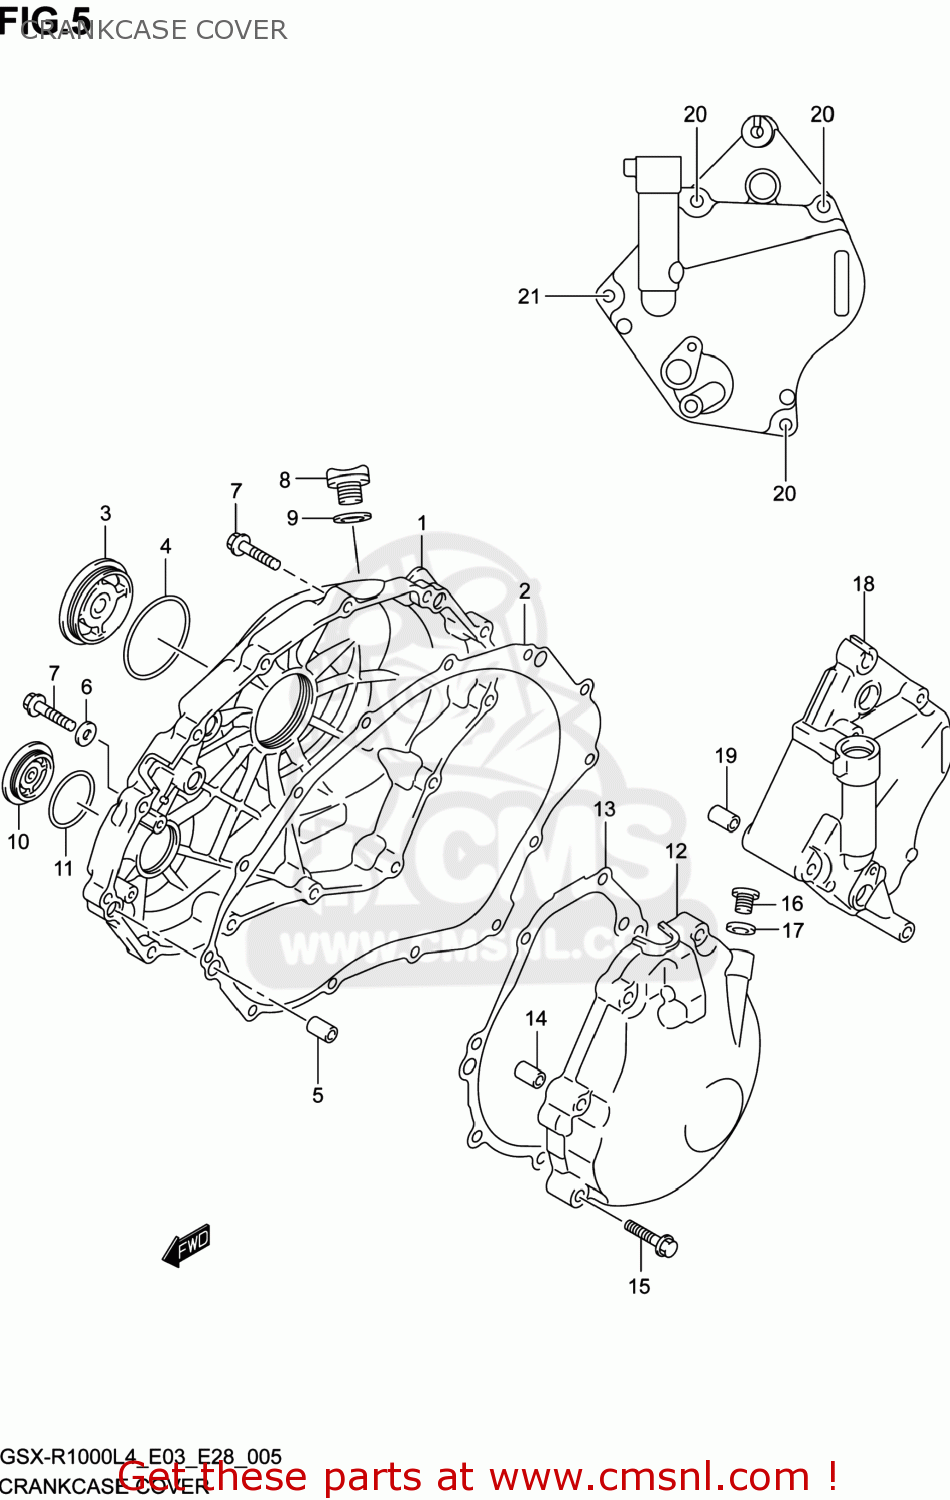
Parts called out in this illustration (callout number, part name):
1	COVER,CLUTCH
2	GASKET,CLUTCH COVER (NAS)
3	CAP,CLUTCH RELEASE ADJUST
4	O RING
5	PIN
6	GASKET(5.8X13X1.2) (NAS)
7	BOLT(6X30)
8	PLUG,ENGINE OIL FILLER
9	O RING(D:3.1,ID:16.8)
10	PLUG
11	O RING(D:3.1,ID:32.7)
12	COVER,GENERATOR
13	GASKET,GENERATOR COVER (NAS)
14	PIN
15	BOLT(6X30)
16	PLUG(10X10)
17	GASKET(10X14X3.6) (NAS)
18	COVER,ENGINE SPROCKET
19	PIN
20	BOLT(6X45)
21	BOLT(6X65)
